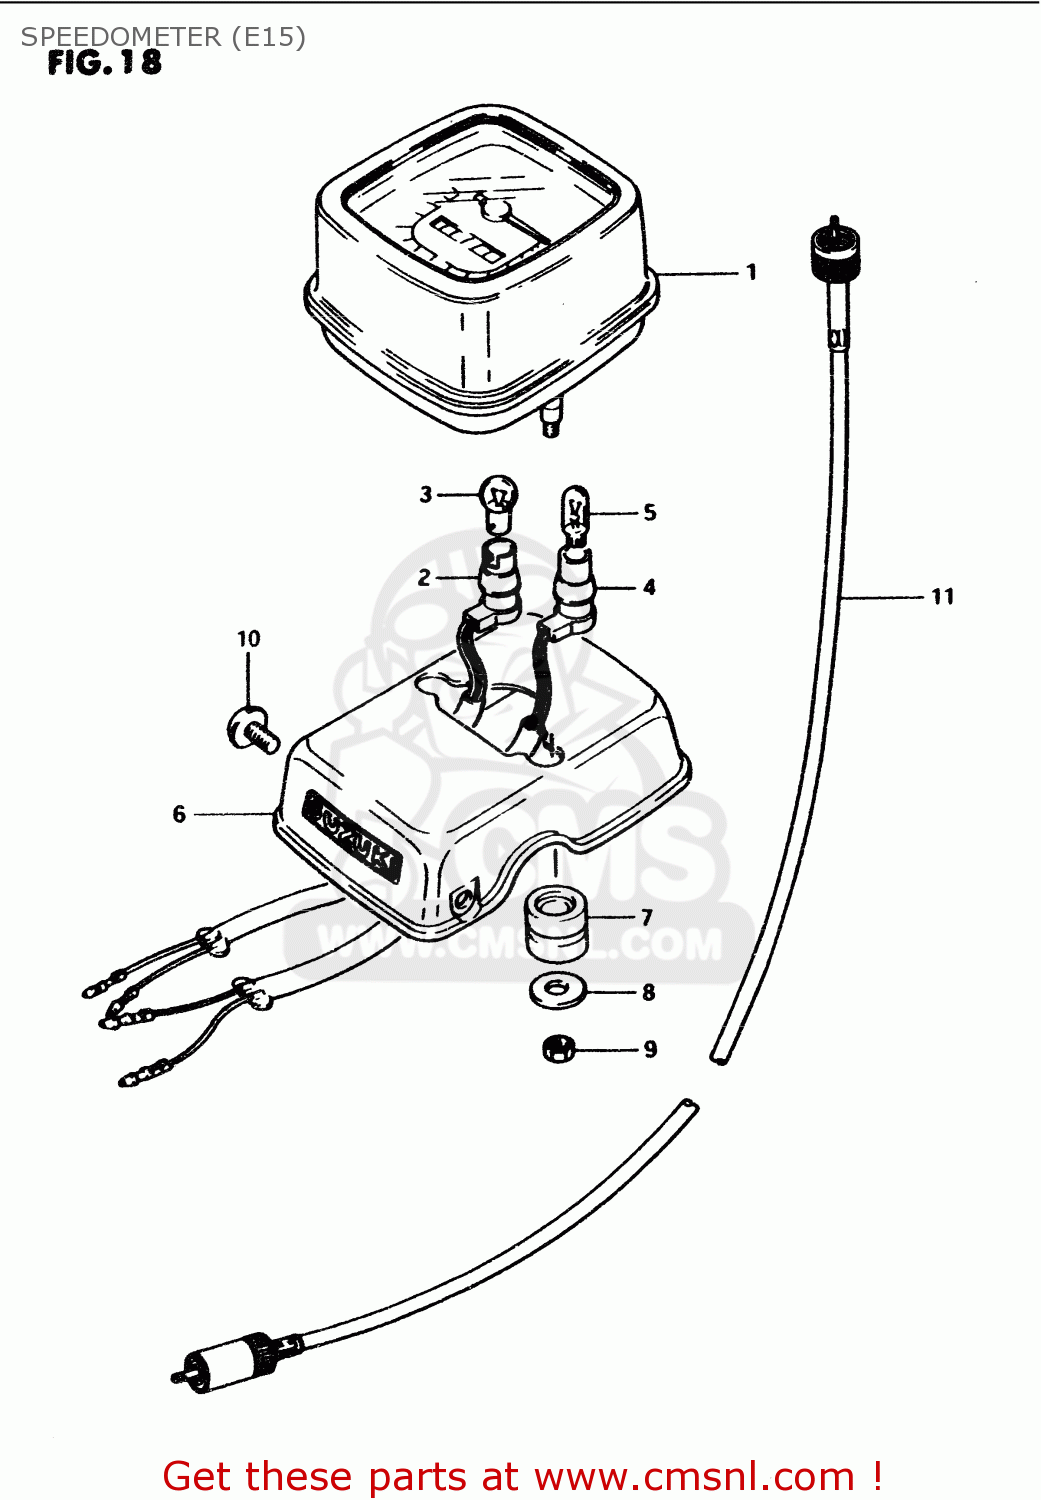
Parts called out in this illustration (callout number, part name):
1	SPEEDOMETER
2	SOCKET,METER
3	BULB(6V/3W)
4	SOCKET,METER
5	BULB(6V,3W)
6	BRACKET,METER
7	CUSHION
8	WASHER (5.5X16X1.2)
9	NUT 5MM
10	SCREW
11	CABLE, SPEEDOMETER
